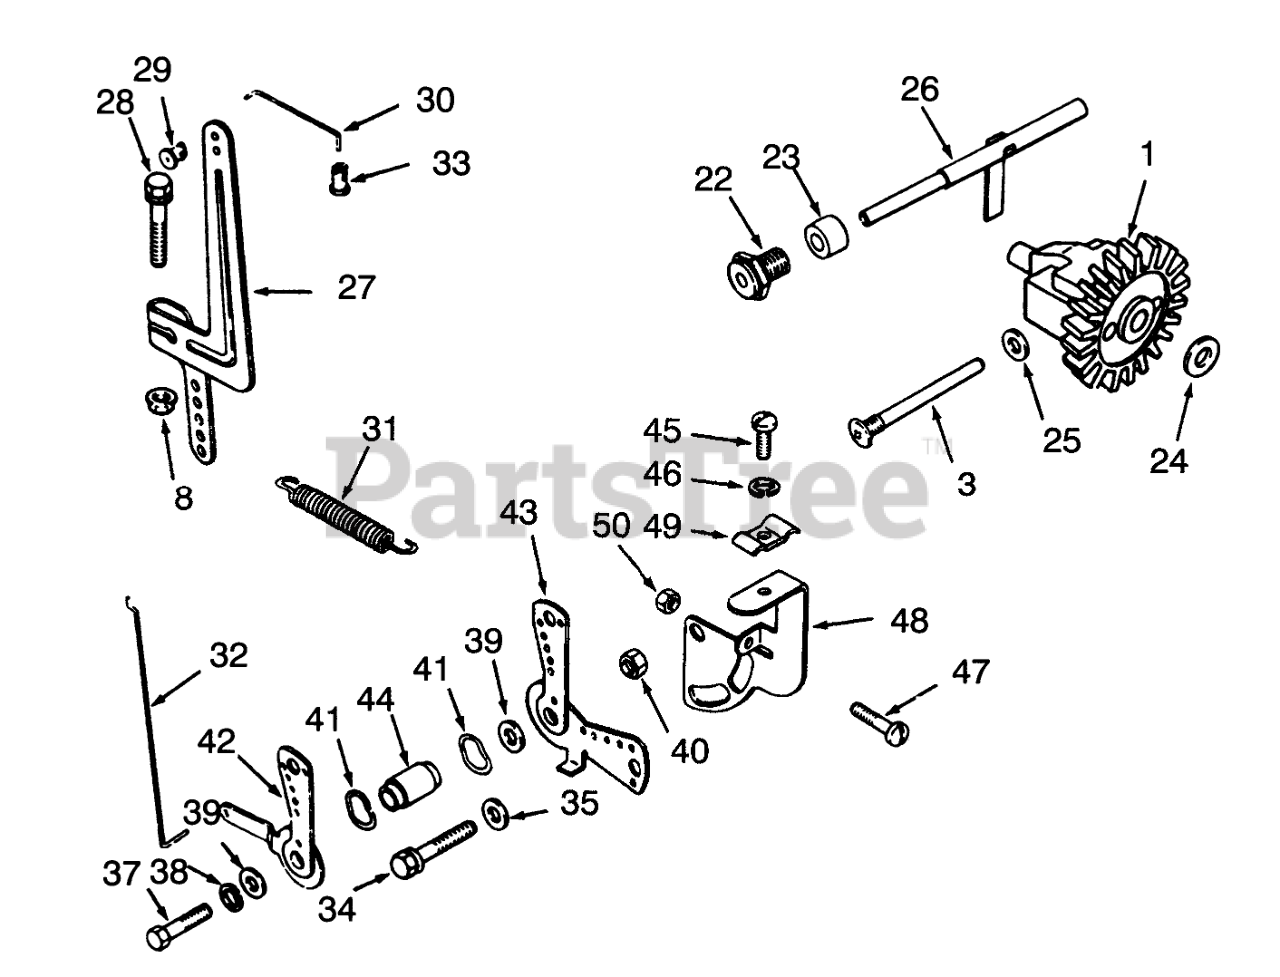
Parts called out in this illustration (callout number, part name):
1	Kit Governor Gear (Includes 24)
3	Govenor Stop Pin
8	Palnut
22	Bushing
23	Spacer
24	Washer
25	Washer
26	Governor Cross Shaft Kit
27	Governor Lever
28	Screw
29	Bushing
30	Carburetor Linkage
31	Spring (Governor to Cab.)
32	Choke Linkage (Carb. to Choke Shaft)
33	Bushing
34	Screw
35	Washer
37	Screw
38	Washer-Lock
39	Washer
41	Washer
42	Choke Control Lever
43	Lever-Throttle Control
44	Space
45	Screw
46	Washer
47	Screw
48	Bracket-Clutch Control
49	Clamp
